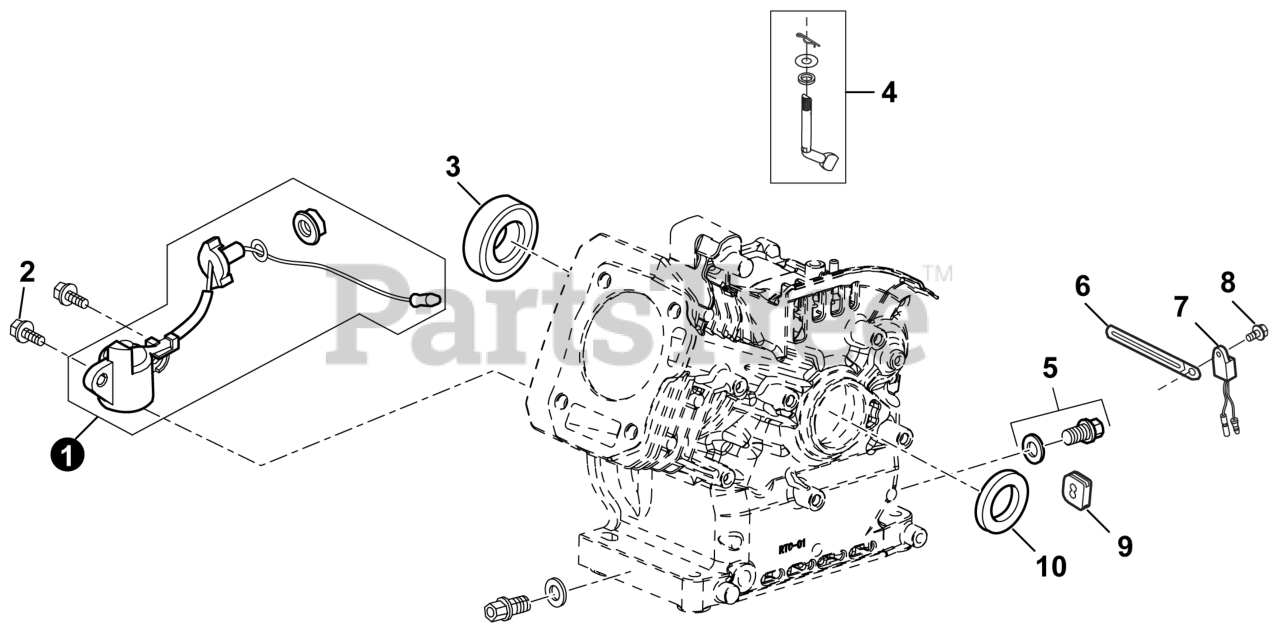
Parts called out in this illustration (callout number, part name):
1	SENSOR, ENGINE OIL
3	BEARING, CRANKSHAFT
4	ARM, GOVERNOR
5	PLUG, OIL DRAIN
7	PROTECTOR, OIL
9	PLUG, RUBBER
10	SEAL, OIL
